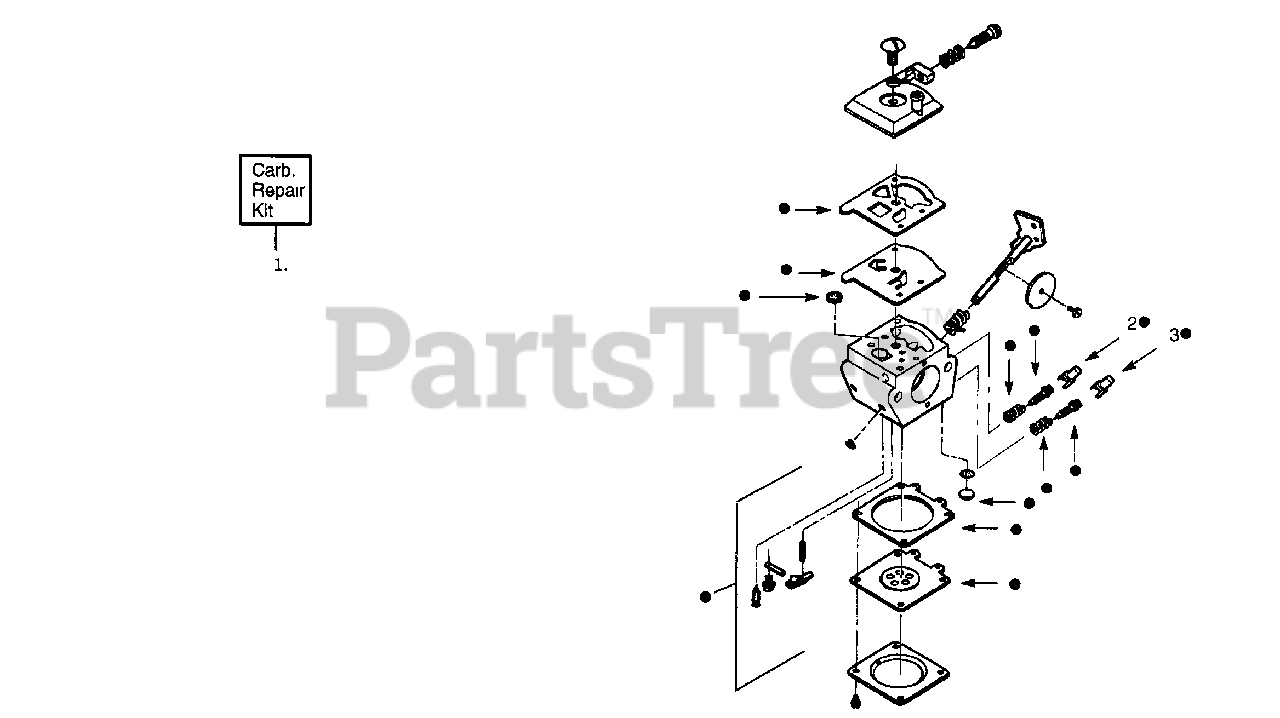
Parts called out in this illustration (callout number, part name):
1	WT-299A
1	WT-380
2	Limiter Cap-Low
3	Limiter Cap-High
